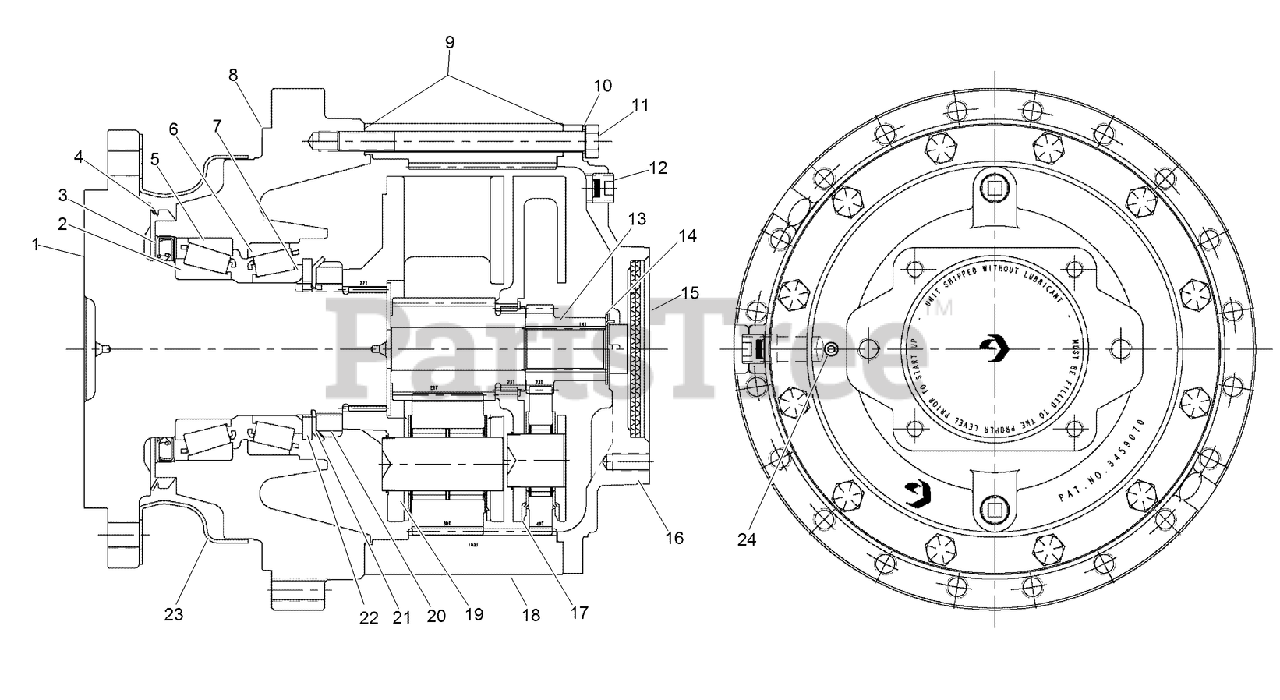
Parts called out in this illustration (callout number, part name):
1	SHAFT - Output
2	BEARING - Cone
3	SEAL - Oil
4	SEAL - V Ring
5	BEARING - Cup
6	BEARING - Cup
7	BEARING - Cone
9	COMPOUND - Sealing
10	WASHER - Flat
11	BOLT - Hex Head
12	PLUG - Pipe
13	GEAR - Sun
14	WASHER - Thrust
15	PLUG - Shipping
17	ASSEMBLY - Pri Carrier
18	GEAR - Ring
19	ASSEMBLY - Sec Carrier
20	NUT - Lock
21	WASHER - Lock
22	WASHER - Thrust
24	PLUG - Pipe
